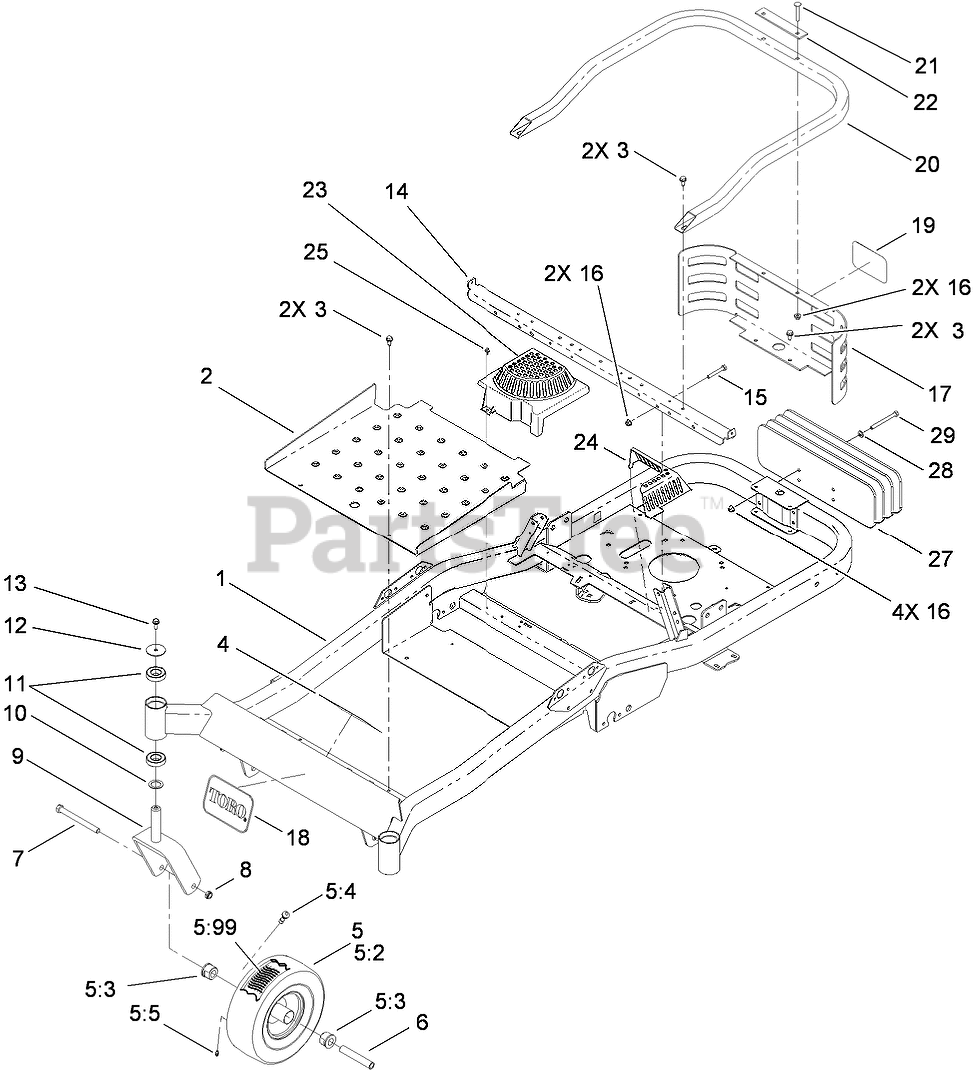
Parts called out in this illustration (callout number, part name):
2	PAN-FLOOR
3	SCREW-HWHTF
4	DECAL-SAFETY
5	TIRE and Wheel ASM (Kenda)
5:2	TIRE-SMOOTH
5:3	BUSHING-FLANGE
5:4	STEM-VALVE
5:5	FITTING-GREASE
5:99	TUBE-INNER
6	BUSHING-SPANNER
7	SCREW-HH
8	NUT-LOCK, NI
9	CASTER FORK ASM
10	WASHER-THRUST
11	BEARING-BALL
12	WASHER
13	SCREW-HHF
14	SUPPORT-SEAT
15	SCREW-HH
16	NUT-HF, NI
17	GUARD-REAR, SHIELD
18	DECAL
20	GUARD-REAR, TUBE
21	Screw-CARR
22	PLATE-SPACER
23	COVER-FAN, RH
24	COVER-FAN, LH
25	SCREW-HHFTF
27	PLATE-WEIGHT, 60 INCH
28	WASHER-PLAIN
29	SCREW-HH
